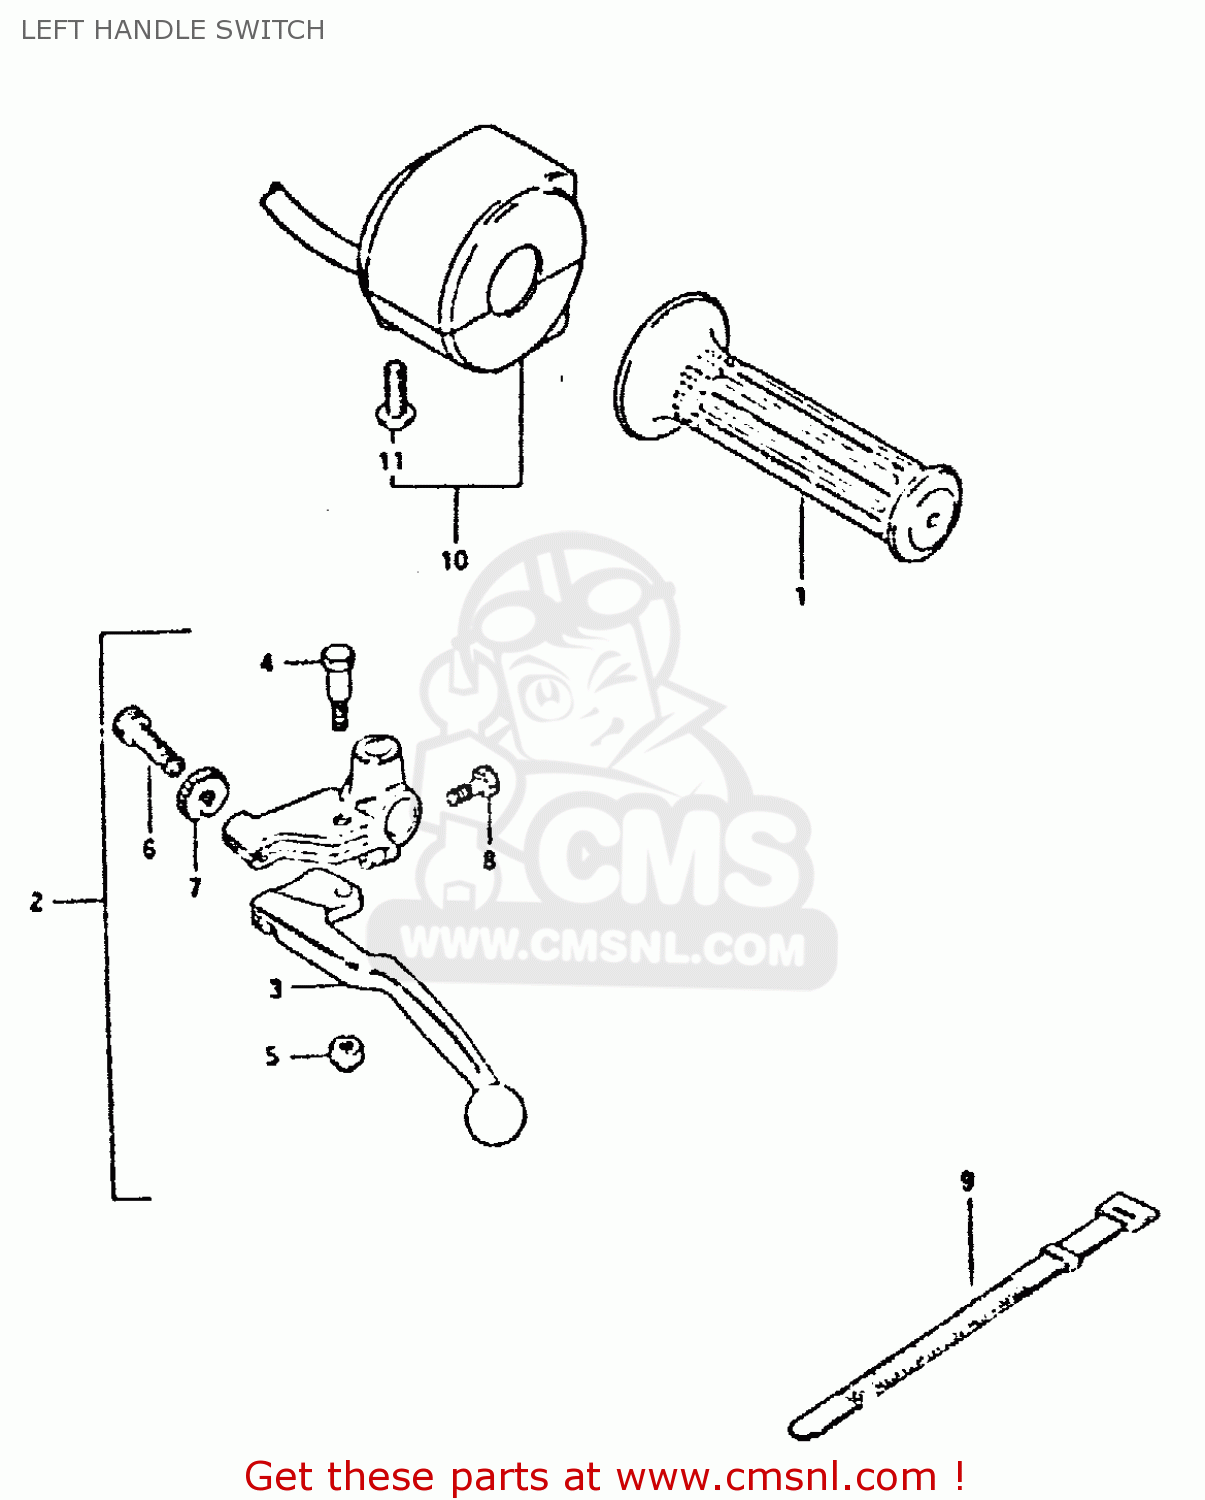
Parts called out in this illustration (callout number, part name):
1	GRIP,LEFT
2	LEVER ASSY, CLUTCH
3	LEVER,CLUTCH
4	BOLT,LEVER
5	NUT 6MM
6	ADJUSTER,CABLE
7	NUT,CABLE ADJUSTER
8	BOLT
9	CLAMP(L:120)
10	SWITCH ASSY, HANDLE LH
11	SCREW
